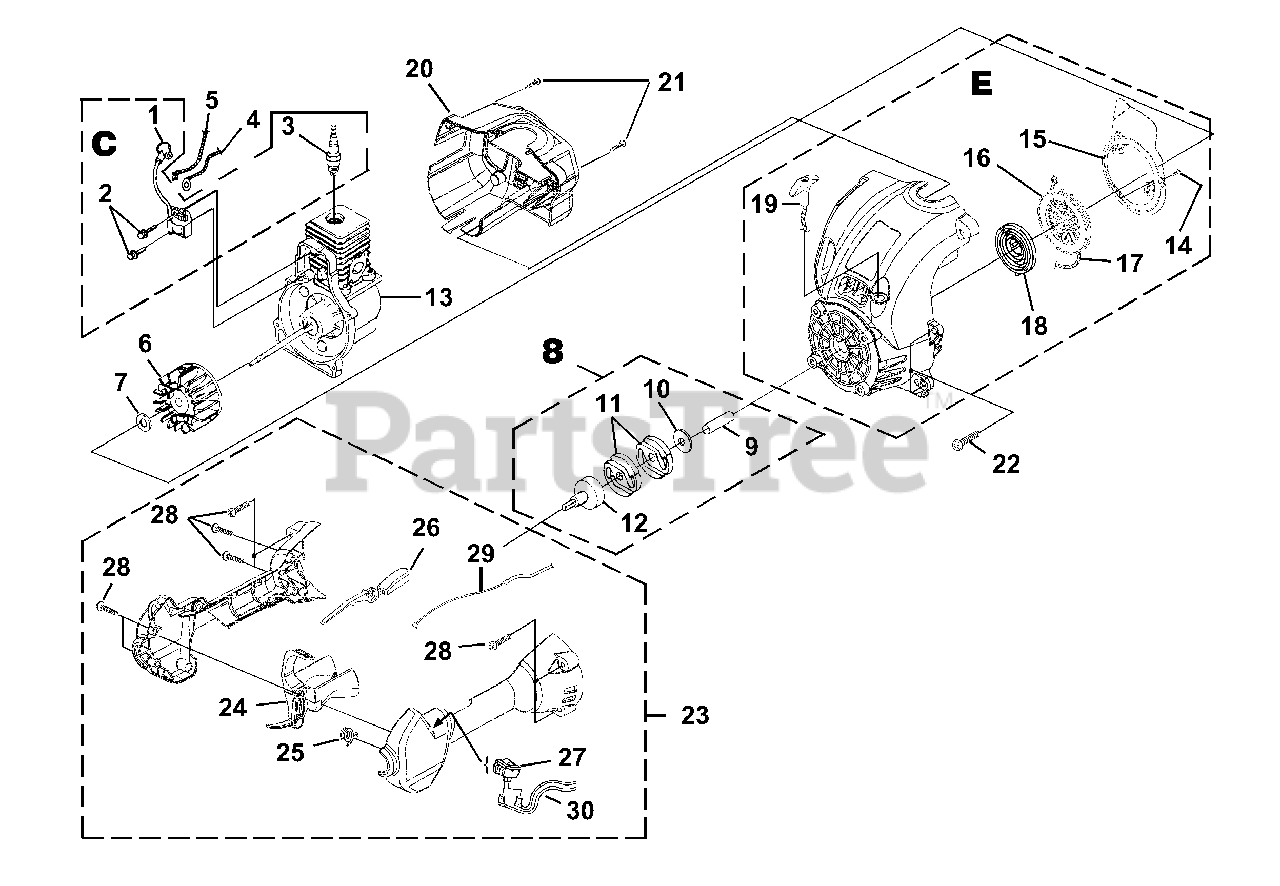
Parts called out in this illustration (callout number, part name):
1	TERMINAL & COVER
2	SCREW-Taptite (8-32 X 1")
3	SPARK PLUG
4	LEAD-Electrical
5	LEAD-Electrical
6	ROTOR KIT
7	WASHER-Flat
8	CLUTCH AND DRUM KIT
9	SPACER
10	WASHER-Flat
11	CLUTCH
12	CONNECTOR AND DRUM
13	SHORT BLOCK
14	SCREW-Thread Form (8-16 X 1/2")
15	BAFFLE-Air
16	PULLEY-Starter
17	ROPE-Starter (42")
18	SPRING & CONTAINER
19	GRIP-Starter (Yellow)
20	HOUSING-Rear Kit
21	SCREW-Plastite (10-14 X 7/8")
22	SCREW-Taptite (10-24 X 3/4")
23	CONTROL HANDLE ASSY.
24	TRIGGER-Throttle
25	SPRING
26	THROTTLE INTERLOCK
27	SWITCH
28	SCREW-Taptite (10-14 X 1")
29	CABLE-Throttle
30	LEAD-Electrical
C	IGNITION KIT
E	COMPLETE STARTER ASSEMBLY
